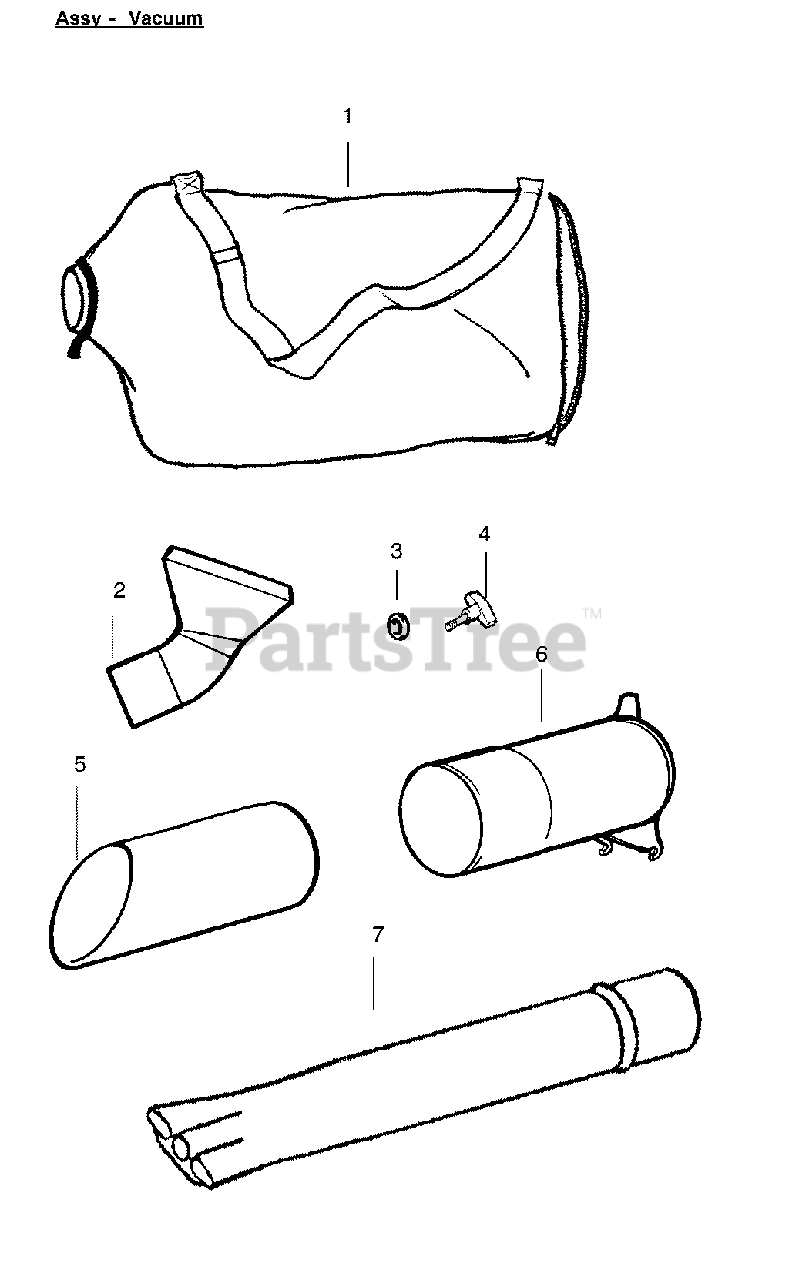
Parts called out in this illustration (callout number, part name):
1	Assy-Vac. Bag w/strap
2	Tube-Elbow Vac
3	Retainer-Vac Tube Knob
5	Tube-Lower Vac
6	Tube-Upper Vac
7	Tube-Blower
